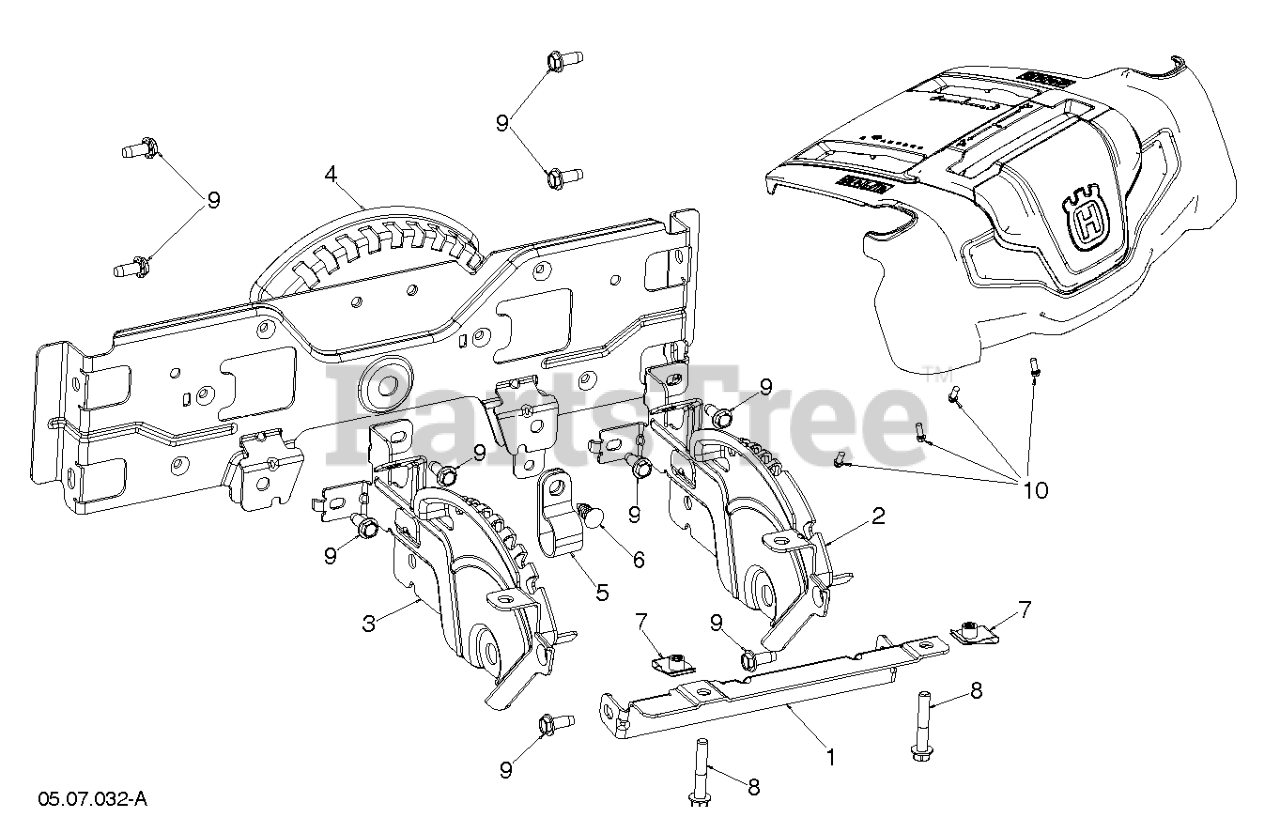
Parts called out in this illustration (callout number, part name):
4	Brackets
5	CLIP.CABLE.BLK
6	FASTENER.PUSH.O.250X0.783
7	NUT.U-CHNL.1/4-20.550DP.350PNL
8	SCREW.HEXCAP.1/4X-20X1.500
9	SCREW 14-20 X 5/8
10	SCREW.HWH.13-16-5.8.BZP
